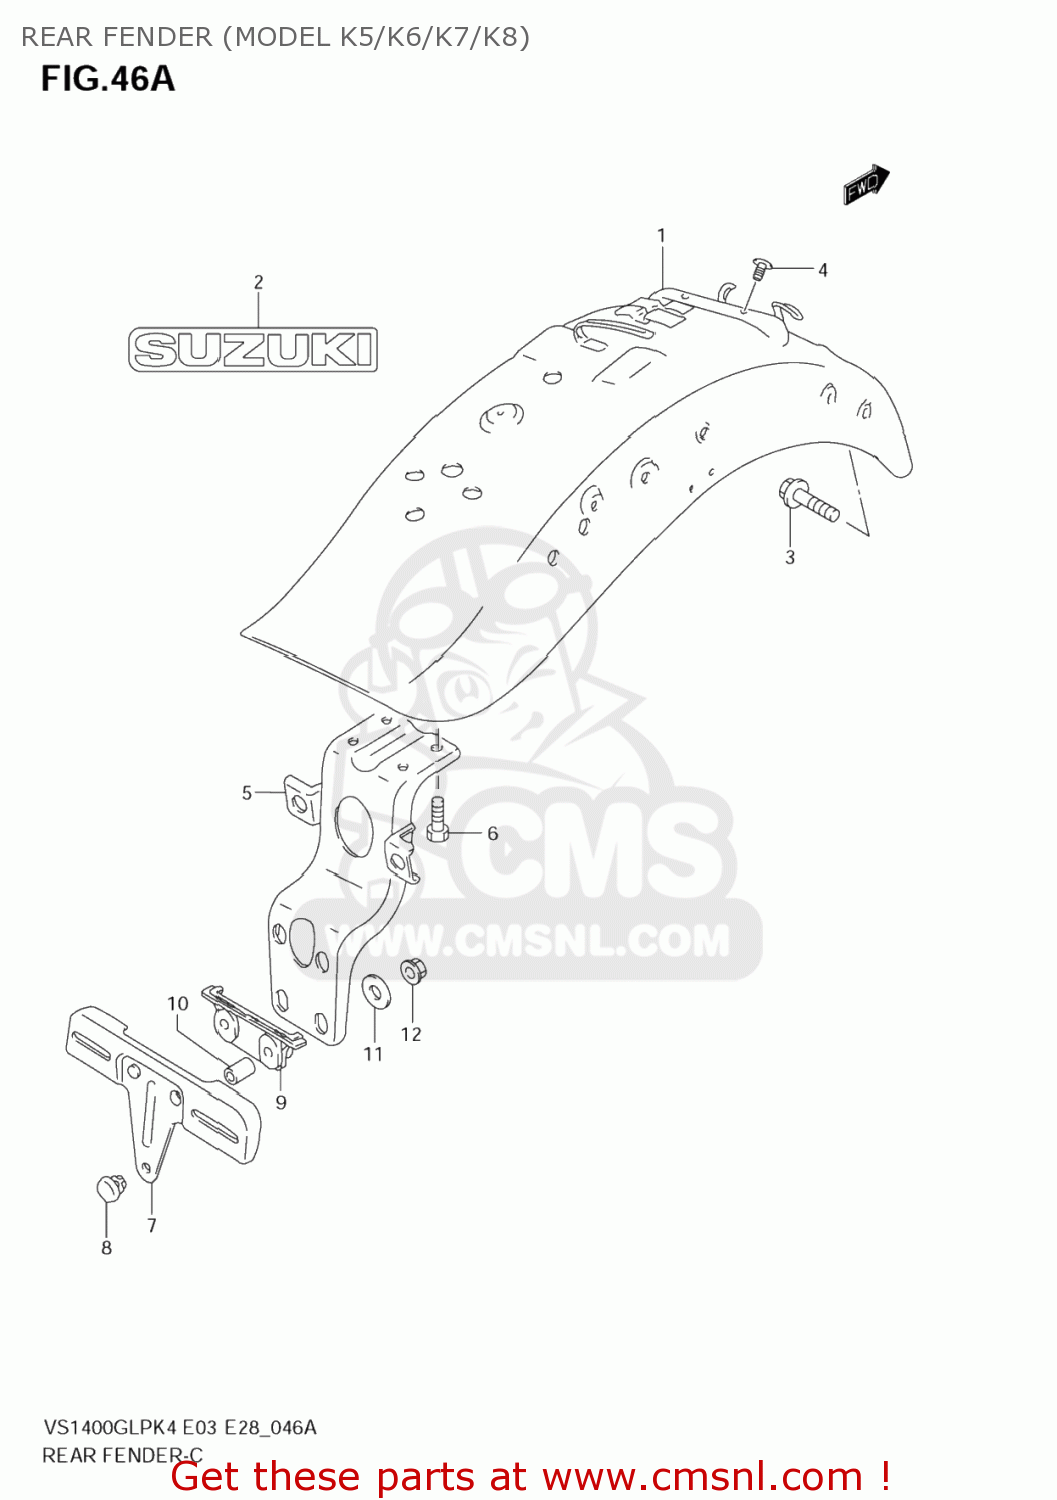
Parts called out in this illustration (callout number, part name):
1	FENDER ASSY,RR
2	EMBLEM,SUZUKI
3	BOLT
4	CAP(OD:12)
5	BRACKET,RR COMBINATION LAMP
6	BOLT
7	PLATE,RR LICENSE
8	CUSHION
9	CUSHION,RR LICENSE PLATE
10	SPACER(5.5X8X14.3)
11	WASHER(5.5X20X1.2)
12	NUT
